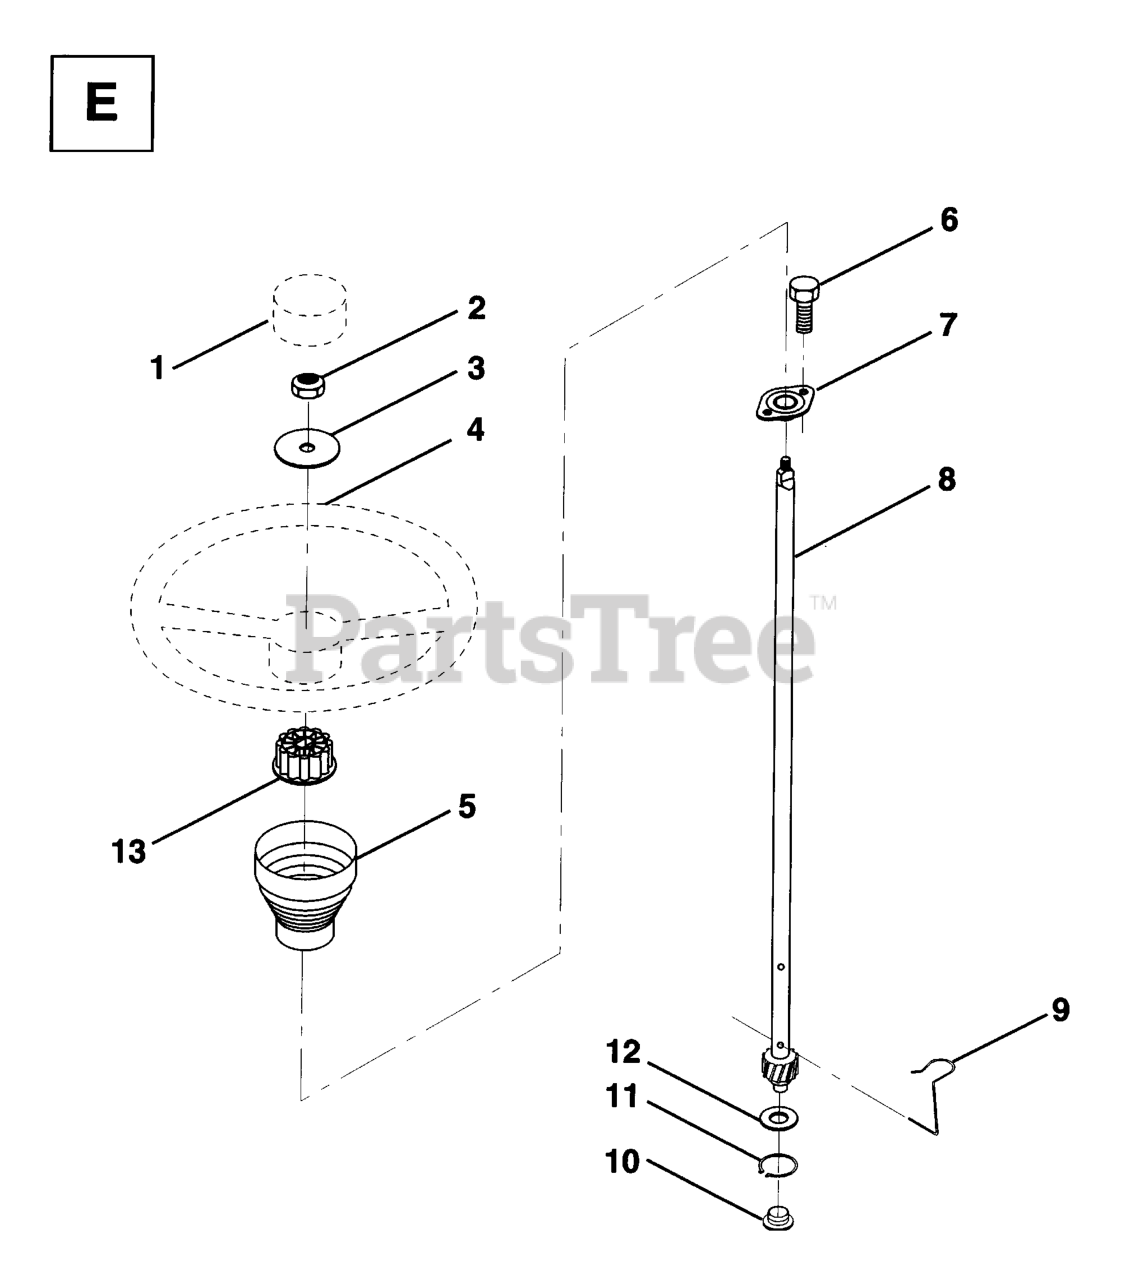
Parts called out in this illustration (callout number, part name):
1	INSERT,STR WHEEL
2	GRIPCO NUT
3	WASHER T
4	STEERING WHEEL
5	STEERING SLEEVE
6	SCREW LT
7	BUSHING-STRG LT
8	SHAFT STEERING
9	STEERING CLIP
10	BUSHING STEER LWR
13	ADAPTER-WHEEL LT
